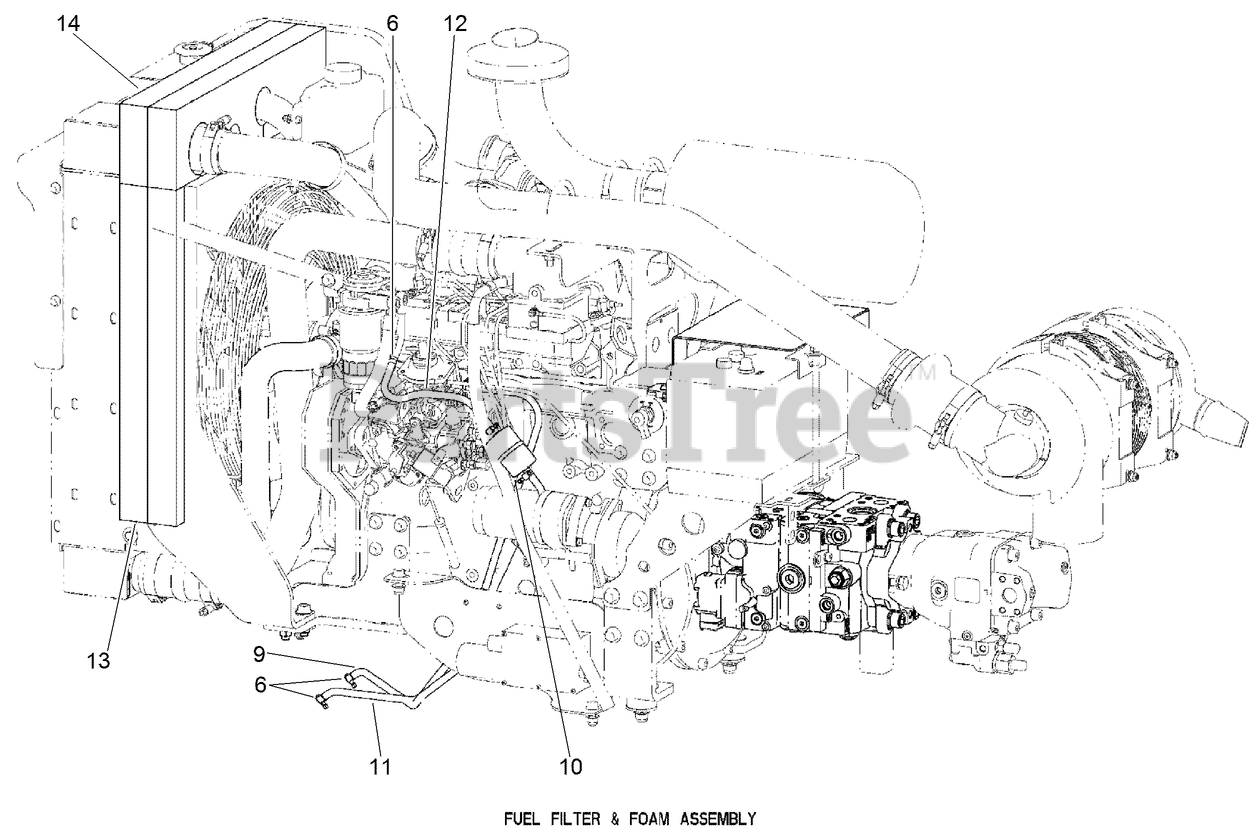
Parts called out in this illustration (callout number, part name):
6	CLAMP - Hose Type M # 06
9	FUEL LINE - 3/8 ID, 42 Length
10	FILTER-INLINE FUEL
11	FUEL LINE - Return, 3/8 ID, 40 Length
12	FUEL LINE - 3/8 ID, 16 Length
13	SEAL-FOAM
14	FOAM SEAL
